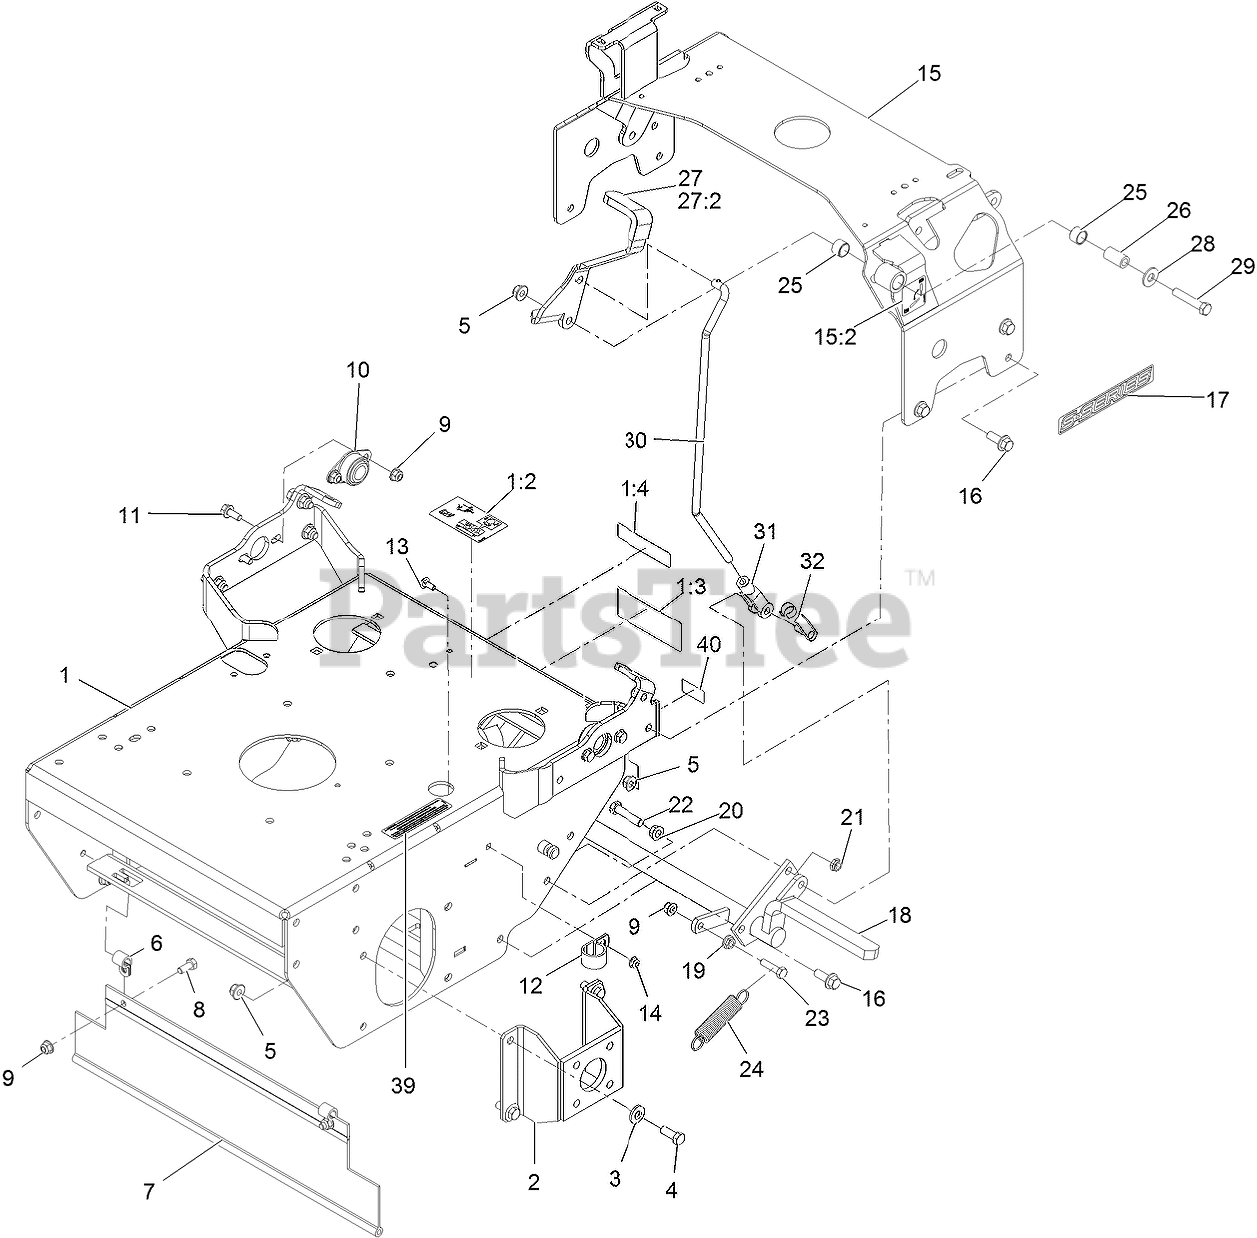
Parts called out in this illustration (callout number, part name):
1	ASM, ENGINE DECK W/ DECAL
1:2	DECAL-DRIVE RELEASE
1:3	DECAL-WARNING, SULKY
1:4	DECAL-WARNING
2	WLD,MOTOR MOUNT 48&52
3	WASHER-BELLEVILLE
4	SCREW-HH
5	NUT-HF, NI
6	CLIP-LOOM
7	SHIELD-DRAG
8	SCREW-HH
9	NUT-HF, NI
10	BEARING-FLANGE, SIDE
11	SCREW-HHF
12	CLIP-LOOM
13	SCREW-CARR
15	ASM, TANK SUPPORT W/ DECA
15:2	DECAL-PARK BRAKE, CE
16	SCREW-HHF 3/8-16 X 1
17	DECAL-S-SERIES
20	NUT-HHF, WHIZ
22	SCREW-HH
23	SCREW-HH
24	SPRING-IDLER
25	SLEEVE-BUSHING
26	BUSHING-PIVOT
27	ASM, BRAKE LEVER W/ GRIP
27:2	GRIP-LEVER
28	WASHER-FLAT
29	SCREW-HH
30	LINKAGE, BRAKE
31	YOKE-LINKAGE, BRAKE
32	PIN-SPRING, CLEVIS
39	DECAL-ARRESTOR, SPARK
40	Decal-Patent Ttco.Com
